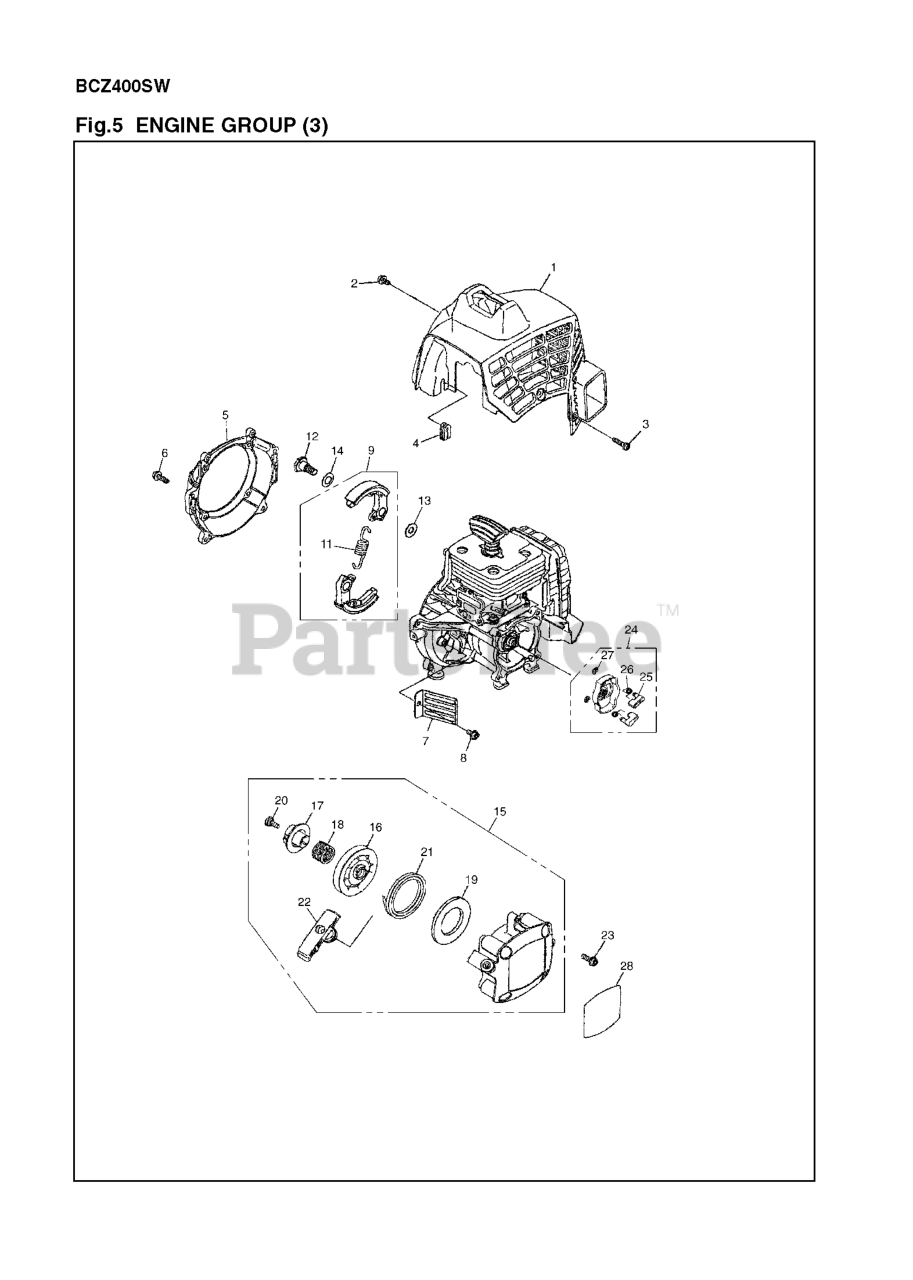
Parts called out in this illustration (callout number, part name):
1	CYLINDER COVER
2	BOLT (RPLS T495051010-11)
3	SCREW, TORX (RPLS T4970-52001)
5	FAN COVER
6	BOLT M5 X 16
8	BOLT (RPLS T495051010-11)
9	SHOE COMP
13	WASHER
15	RECOIL ASSY
17	PLATE, CAM
18	SPRING, DAMPER
19	SPRING,SPIRAL
24	PULLEY ASSY
27	E-RING
28	LABEL, RECOIL
